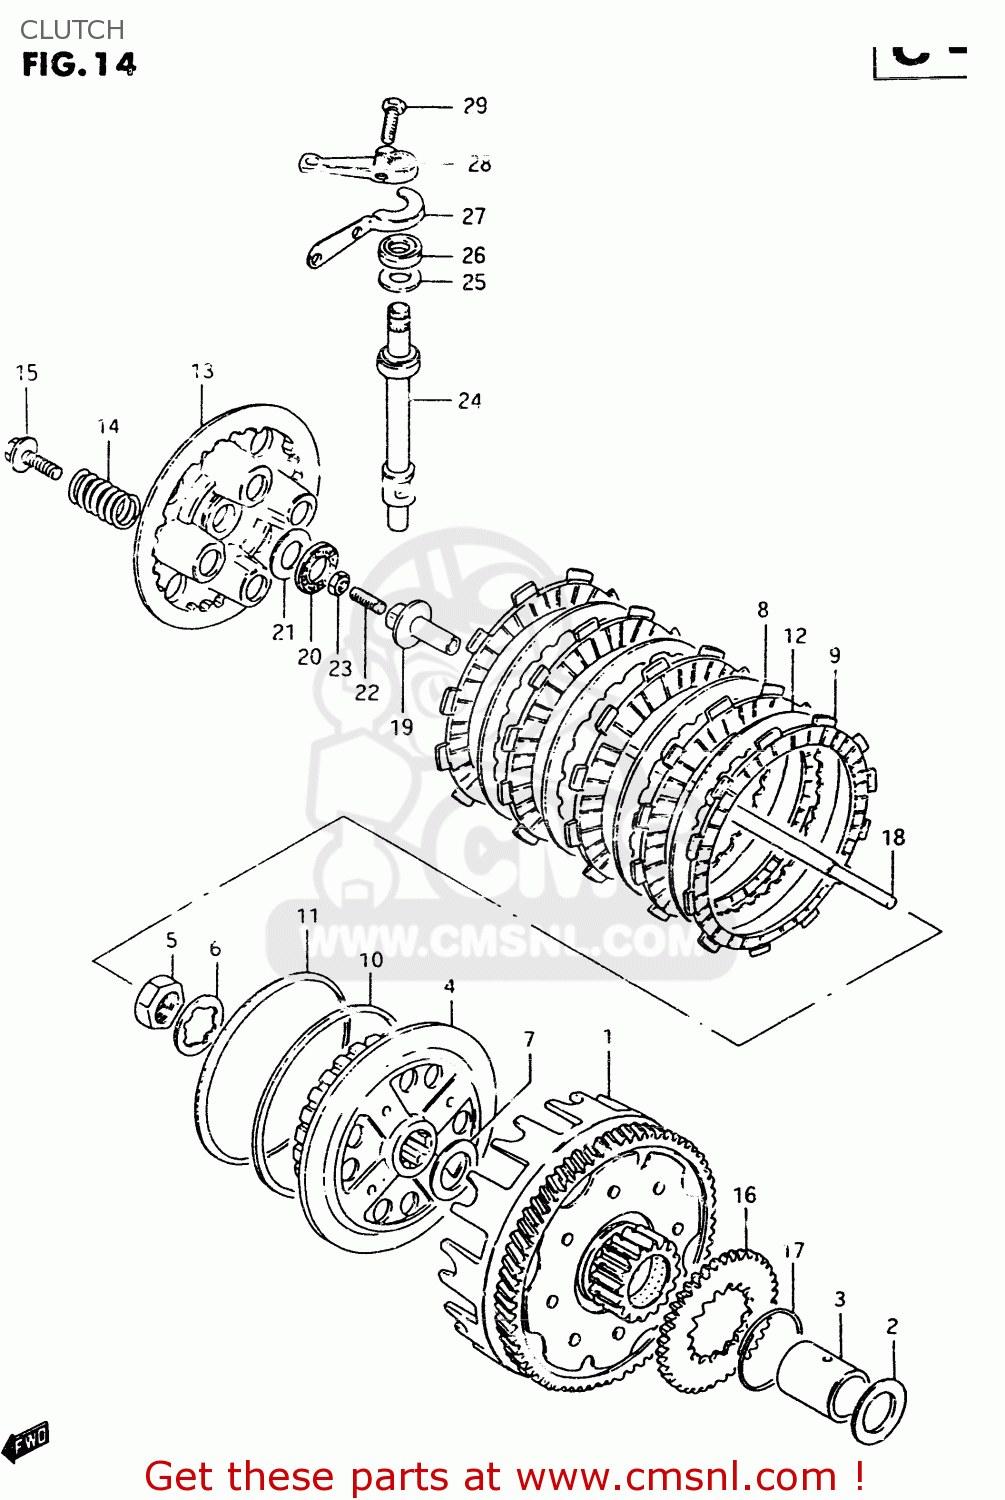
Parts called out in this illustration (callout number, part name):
1	GEAR ASSY,PRI DRIVEN
2	WASHER
3	SPACER(22X28X37.5)
4	HUB,CLUTCH SLEEVE
5	NUT
6	WASHER,LOCK
7	WASHER
8	PLATE,CLUTCH DRIVE (NAS)
9	PLATE,CLUTCH DRIVE(T:3.5) (NAS)
10	SEAT,WAVE WASHER(T:1.4)
11	WASHER
12	PLATE,CLUTCH DRIVEN(T:1.6) (NAS)
13	DISC,CLUTCH PRESSURE
14	SPRING
15	BOLT(6X16)
16	GEAR,OIL PUMP DRIVE
17	CIRCLIP
18	ROD,CLUTCH PUSH
19	PIECE,CLUTCH PUSH
20	BEARING(15X28X2)
21	WASHER(15.5X28X1)
22	SCREW(6X25)
23	NUT
24	CAMSHAFT,CLUTCH RELEASE
25	WASHER (14.2X22X1)
26	OIL SEAL
27	PLATE,CLUTCH RRS CAMSHAFT SEAL
28	ARM,CLUTCH RELEASE
29	BOLT
